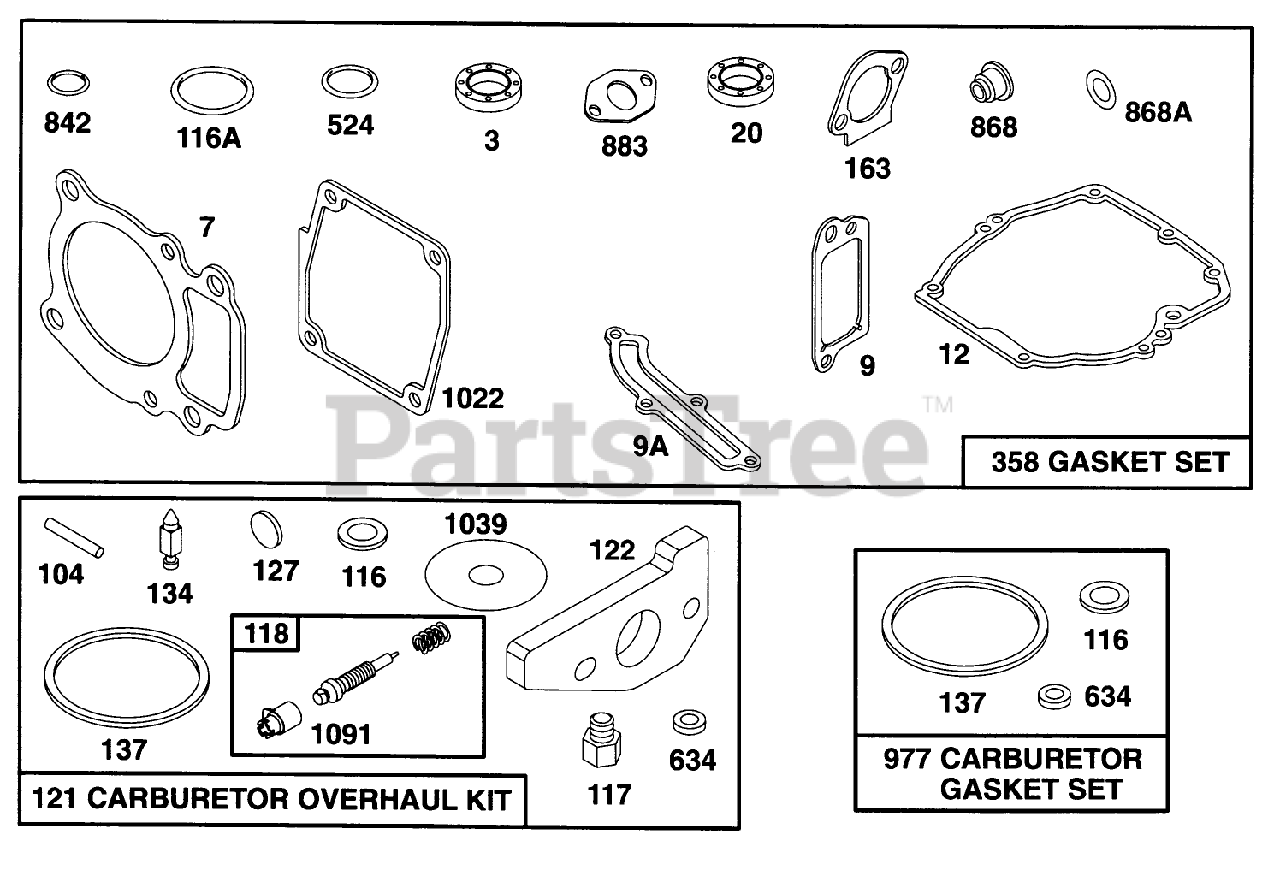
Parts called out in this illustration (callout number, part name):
7	CYLINDER HEAD GASKET
12	ENGINE BASE GASKET
20	SEAL-OIL
116	SEALING GASKET
116A	O RING SEAL
121	KIT-CARBURETOR OVERHAUL
122	ADAPTER ASSEMBLY
134	VALVE-FLOAT
137	FLOAT BOWL GASKET
163	AIR CLEANER GASKET
358	GASKET SET
524	O-RING
842	O-RING
977	CARBURATOR GASKET SET
1022	ROCKER COVER GASKET
1039	FLOAT LIMITER
1091	CAP - LIMITER
